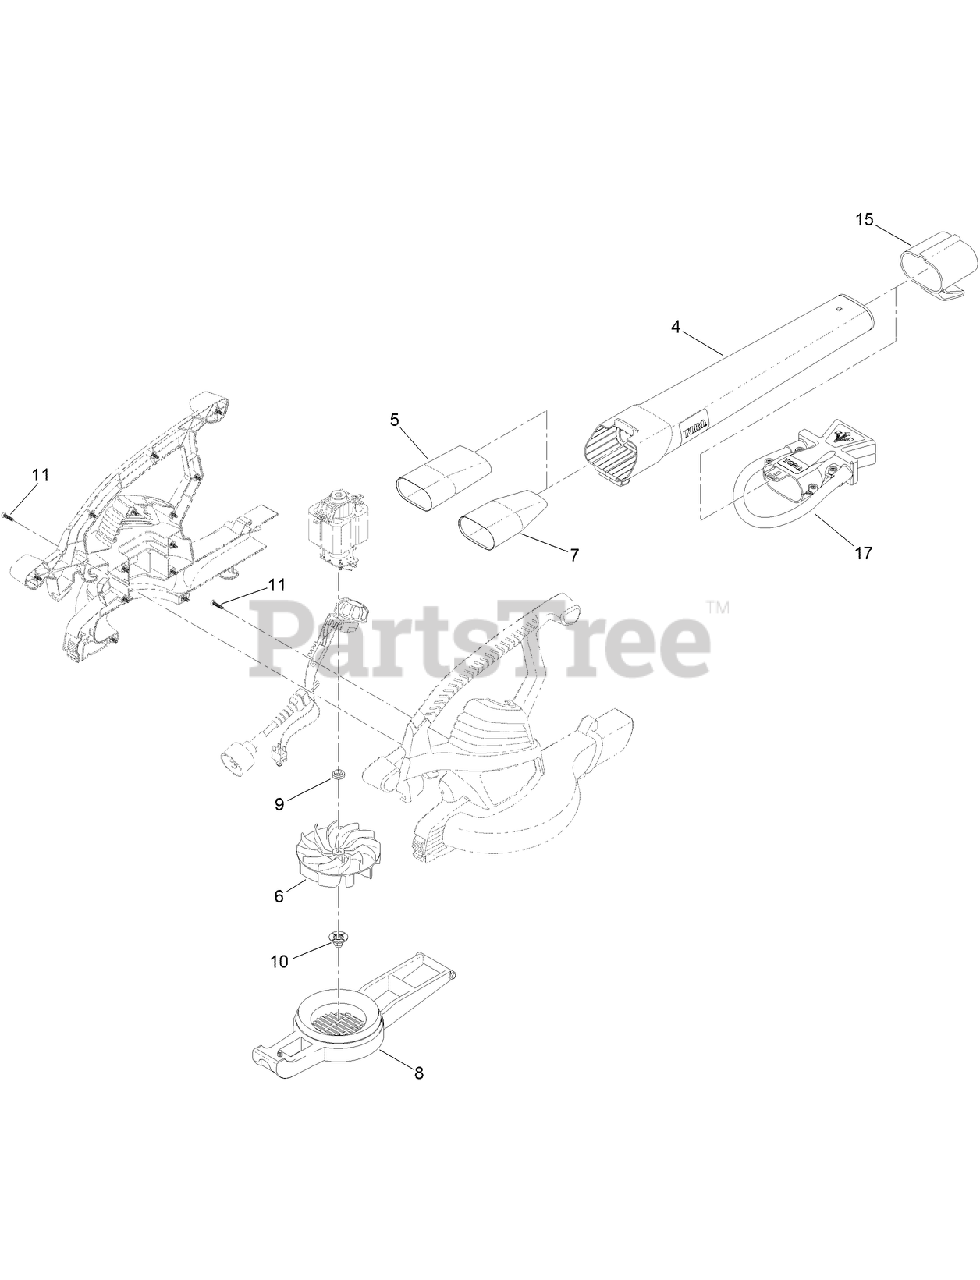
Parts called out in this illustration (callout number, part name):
4	TUBE-BLOWER
5	TUBE-INSERT
7	INSERT-TUBE, MPH
8	COVER-INLET
9	BUSHING-MOTOR
10	NUT-IMPELLER
11	SCREW-PPH
15	ADAPTER-WRAP, CORD
17	OSCILLATOR NOZZLE ASM
